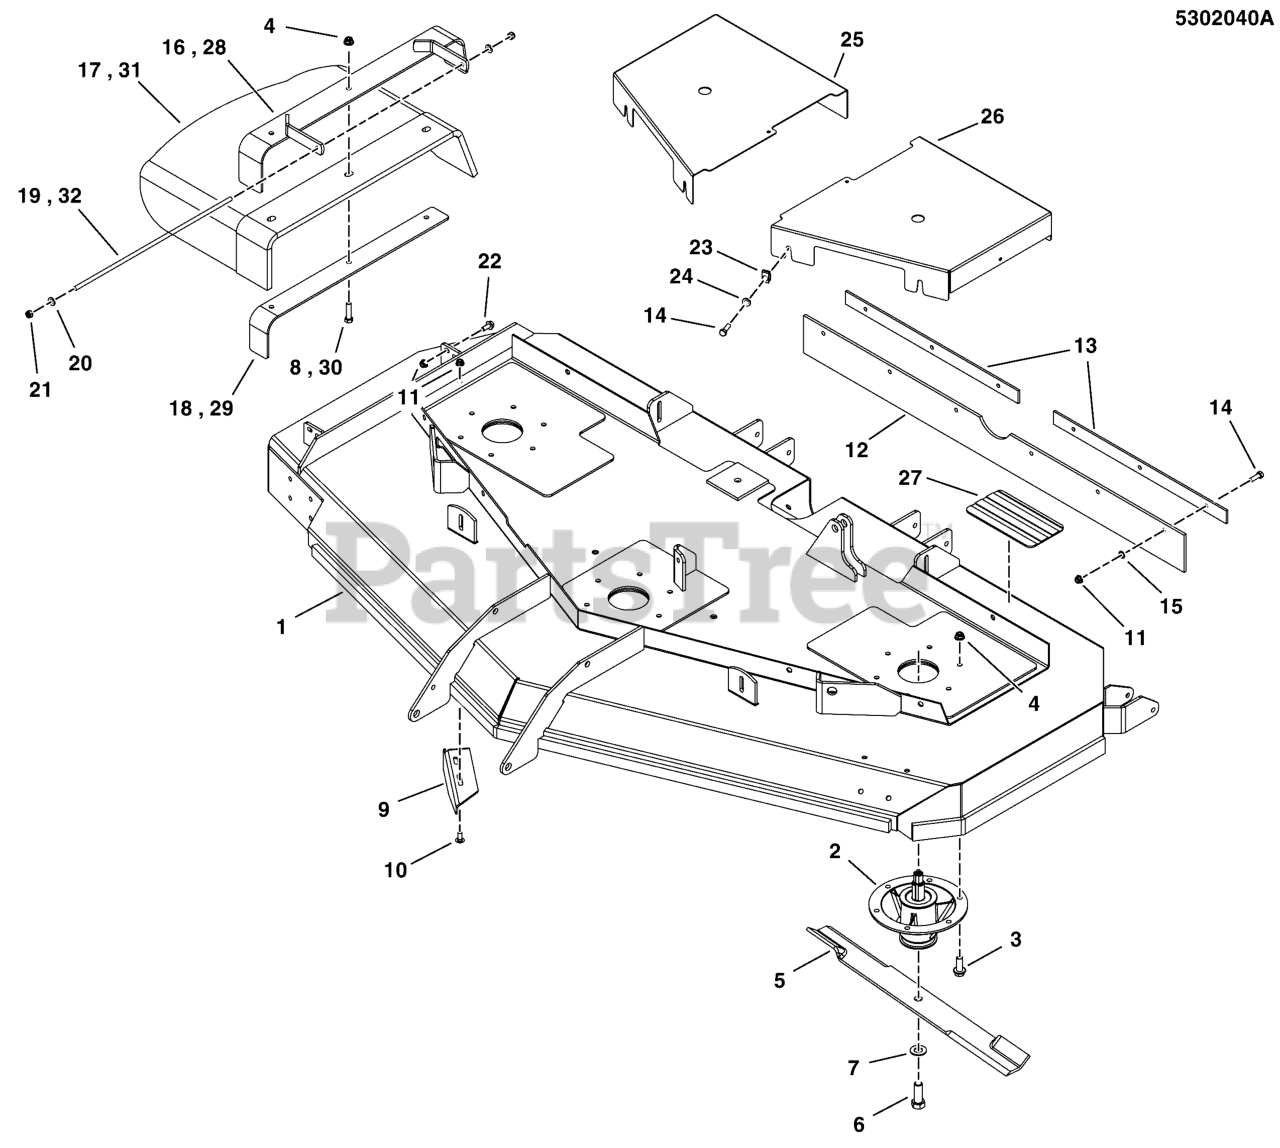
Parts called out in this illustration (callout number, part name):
1	DECK SHELL W/ DECALS, 72 - F800X
2	SPINDLE ASSM, CAST IRON 8.0-6 BOLT
3	BOLT, 3/8-16 X 1-1/4, FLANGE, GD 5, CZ
4	NUT, 3/8-16 HEX NYLOCK FLANGE
5	BLADE, 25 X 25 X 2.50, HIGH LIFT (SET OF 3)
6	BOLT, 5/8-11 X 1-3/4 GD8
7	WASHER, 5/8 GRADE 8, YZ
8	BOLT, 3/8-16 X 1-1/2" GD5 CZ
9	PLATE, DEFLECTOR, 72 - BLK
10	BOLT, 5/16-18 X 3/4, CARRIAGE
11	NUT, 5/16-18 HEX NYLOCK FLANGE
12	FLAP, STRIPER, 72 DECK
13	PLATE, SUPPORT, 72, S800X - RED
14	BOLT, 5/16-18 X 1 GD5 YZ
15	5/16 PUSH-ON NUT RETAINER, STL, CZ
16	WELD, FRAME, CHUTE, 72 - BLK
17	CHUTE, DISCHARGE, BEND RUBBER (SV)
18	SUPPORT, DICHARGE CHUTE, 61/72 - BLK
19	ROD, MOUNT, CHUTE, 72, CZ
20	WASHER, 5/16" SAE
21	NUT, 5/16-24 HEX NYLON LOCK
22	BOLT, 5/16-18 X 3/4 GD5
23	BODY CLIP, 5/16-18-7GA MATERIAL
24	WASHER, 5/16 GD.9 FLAT
25	GUARD, DECK - RH - RED
26	GUARD, DECK - LH - RED
27	SAFETY WALK, 4.00 X 7.50
28	MOUNT
29	SUPPORT, DISCHARGE CHUTE - BLK
30	BOLT, 3/8-16 X 1-1/2, CARRIAGE, GD5, CZ
31	CHUTE, RUBBER DISCHARGE
32	ROD, MOUNT, CHUTE 61, CZ
